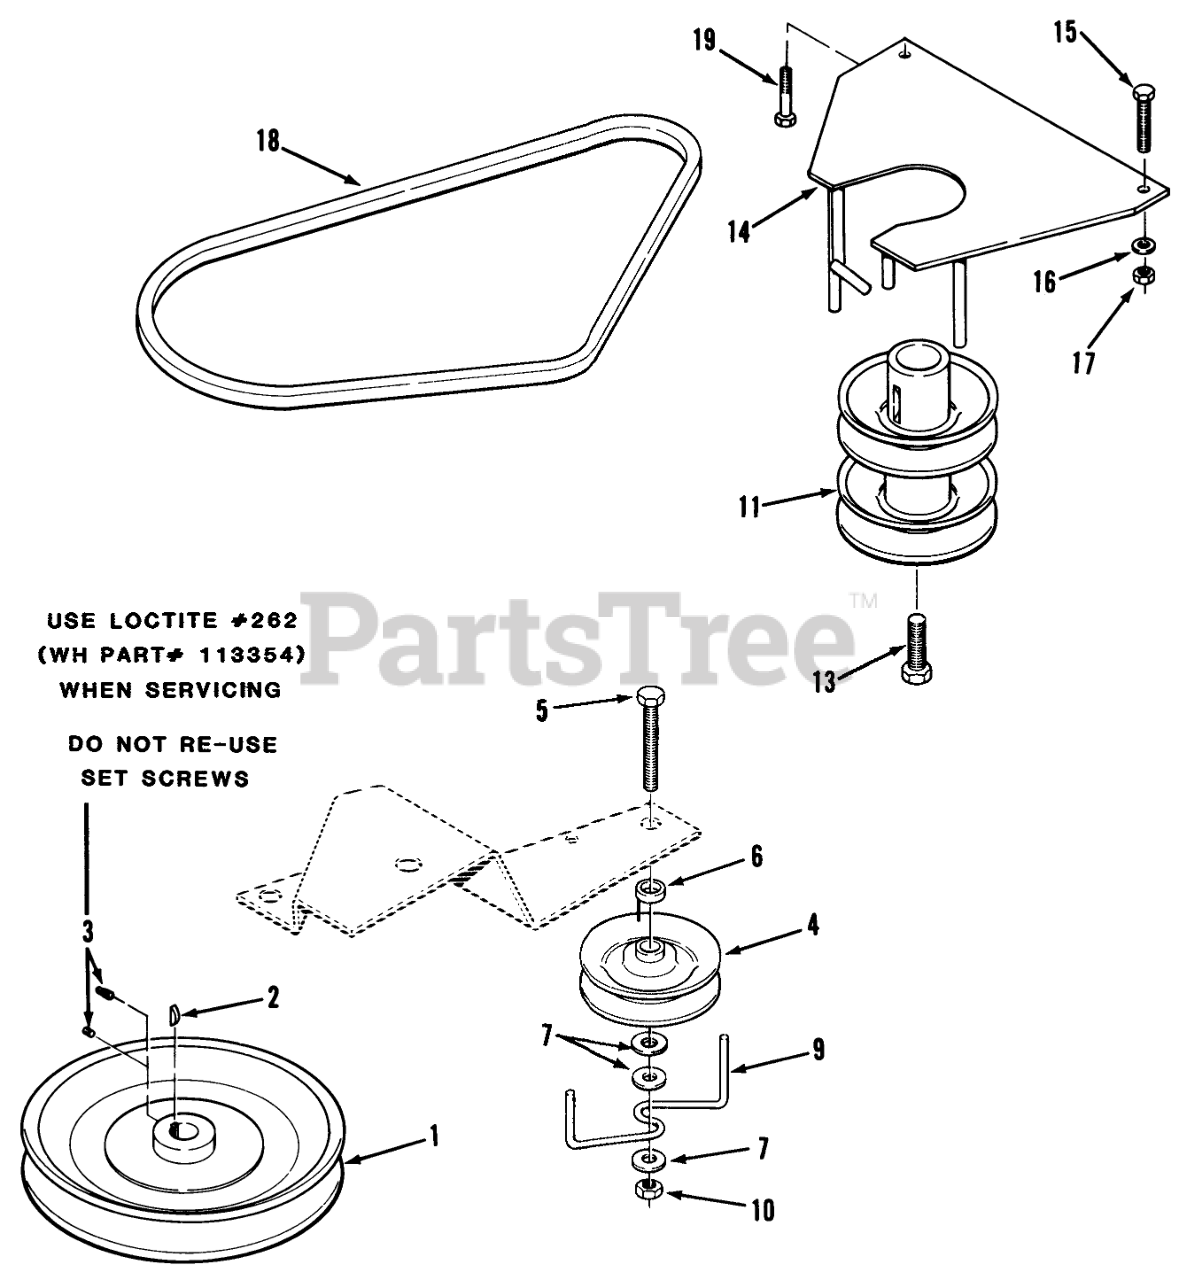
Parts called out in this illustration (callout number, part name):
1	PULLEY TRANSMISSION
2	KEY-HI-PRO
3	Set Screw
4	PULLEY-IDLER STATION
5	Bolt
6	SPACER
7	Washer
9	GUIDE - BELT
10	NUT-HEX, JAM
11	PULLEY-ENGINE
13	HEX HD CAP SCREW
14	Engine Pulley Belt Guide
15	HHCS
16	WASHER 5/16 SAE
17	Nut
18	BELT-V
19	Screw
